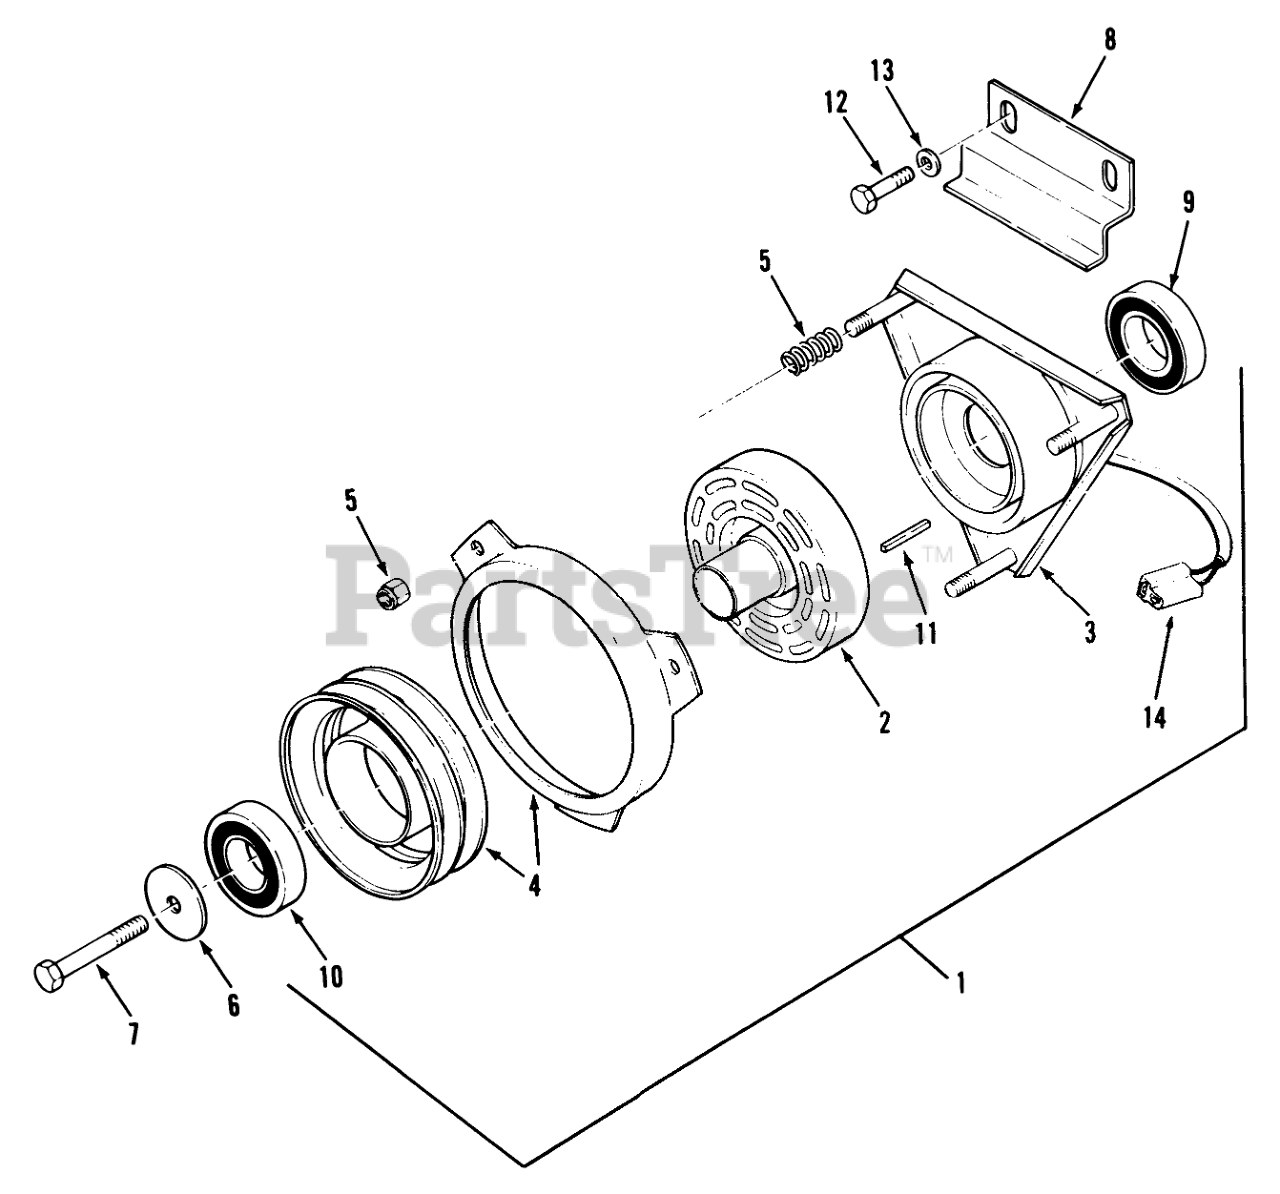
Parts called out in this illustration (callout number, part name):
1	Electric Clutch-Complete (Incl. Items #2, 3, 4, 5, 9, 10, & 14)
2	Rotor
3	Field (Incl. Item #9)
4	Armature & Pulley (Incl. Item #10)
5	Spring & Nuts
6	RETAINER-BEARING
7	SCREW-HH
8	BRACKET-CLUTCH B
9	BEARING-FIELD ASS'Y
10	Bearing
11	KEY-SQUARE
12	Bolt
13	Washer
14	CONNECTOR BODY B
